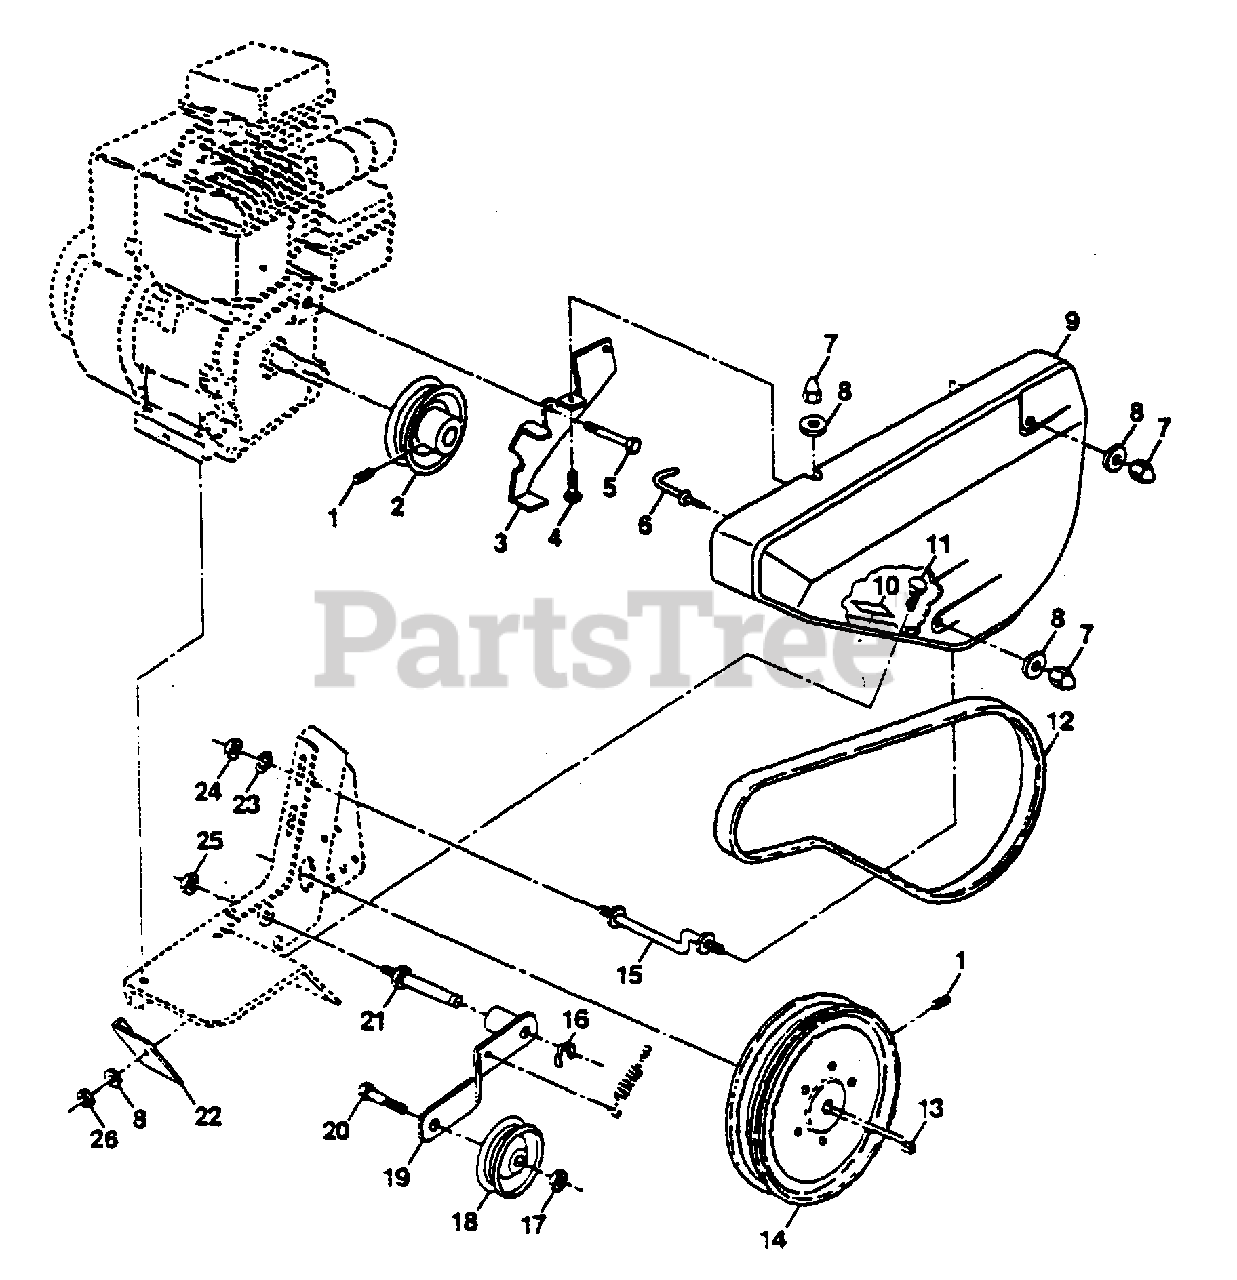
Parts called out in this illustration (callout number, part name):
1	Screw, Set, Forged Socket, Headless 5/16-18 x 3/8 (AYP part number)
2	Pulley, Engine
3	Bracket Assembly, Guard, Belt (AYP part number)
4	Bolt, Carriage 1/4-20 x 1/2 (AYP part number)
5	Bolt, Hex 1/2-20 x 3/4 (AYP part number)
6	Keeper, Belt, Transmission Pulley (AYP part number)
7	Nut, Cap 1/4-20 (AYP part number)
8	Washer 9/32 x 5/8 x 16 Ga. (AYP part number)
9	Guard, Belt (AYP part number)
10	Pad, Idler (AYP part number)
11	Bolt, Carriage 1/4-20 x 3/4 (AYP part number)
12	V-Belt (AYP part number)
13	Key, Square (AYP part number)
14	Pulley, Transmission (AYP part number)
15	Bolt, Belt Guard
16	Ring, Klip (AYP part number)
17	Nut, Hex, Jam 3/8-16 (AYP part number)
18	Pulley, Idler (AYP part number)
19	Idler Arm Assembly (AYP part number)
20	Bolt, Hex 3/8-16 x 1-1/4 (AYP part number)
21	Shaft, Idler Arm (AYP part number)
22	Shield, Dirt (AYP part number)
23	Washer, Lock 1/4 (AYP part number)
24	Nut, Hex 1/4-20 (AYP part number)
25	Nut, Hex, Jam 5/16-18 (AYP part number)
26	Locknut, w/Insert 1/4-20 (AYP part number)
